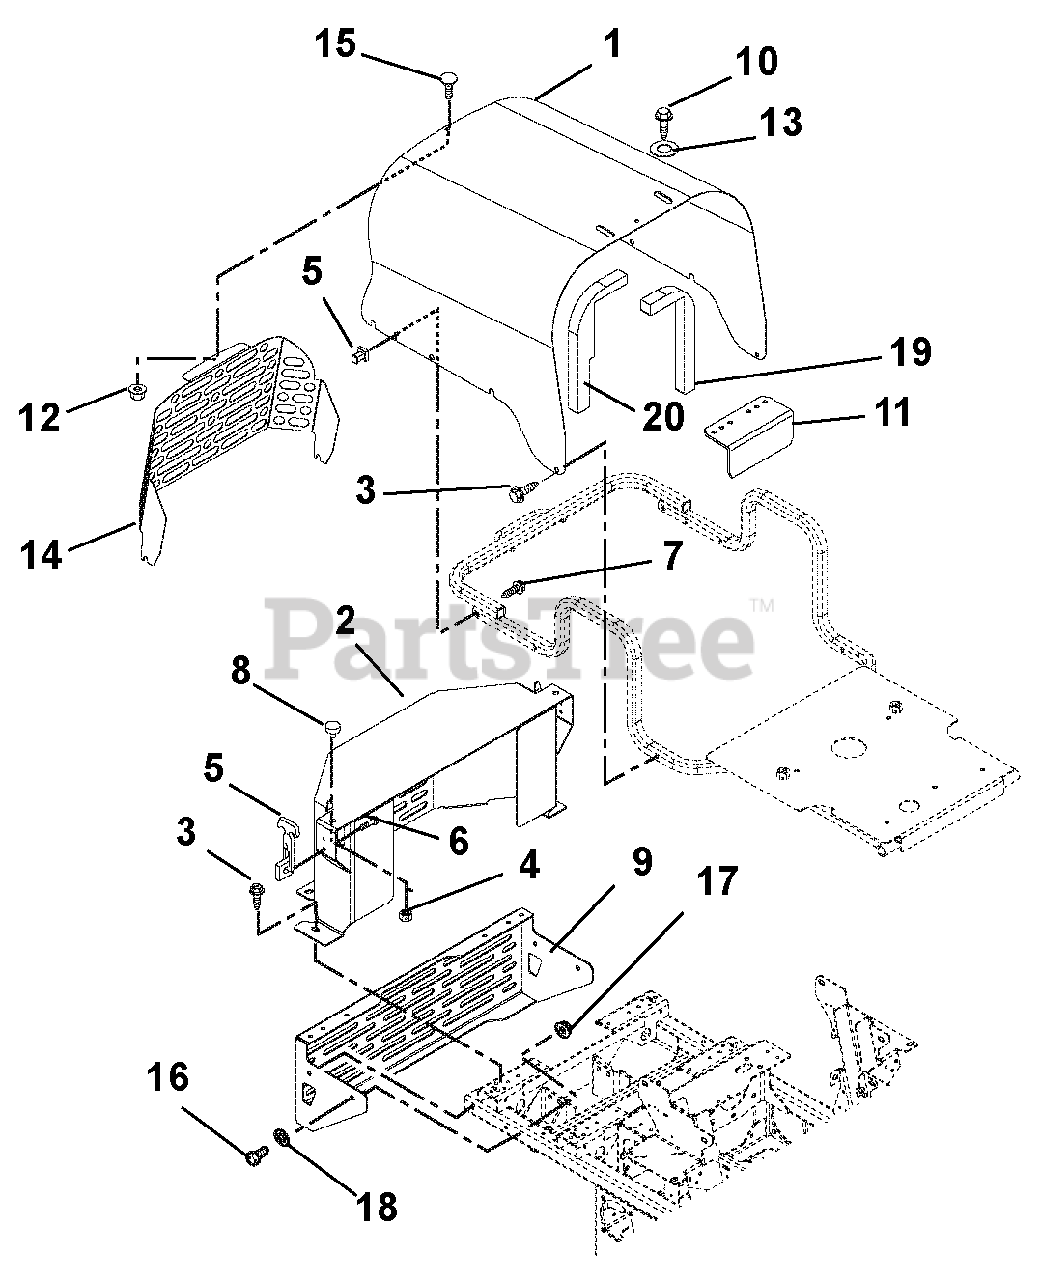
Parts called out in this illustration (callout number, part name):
2	Diesel Belt Guard
3	Screw, Tapping .38-16 x .75 Hex Washer Head
4	Nut, Spin Lock, Flange .312-18
5	Latch, Rubber
6	Screw, Machine 10-24 x .50 Hex Washer Head
7	Screw, Machine 10-24 x 1.50 Hex Washer Head
8	Bumper, Rubber
9	Bumper, Weldment, Rear Diesel
10	Screw, Tapping .25-20 x .50 Hex Washer Head
11	Guard, Radiator Cap
12	Nut, Locking Top Flange .25-20
13	Washer, Flat Steel .281 x .62 x .065
14	Guard, Hood
15	Bolt, Round Head Square Neck .25-20 x .50 Grade 5
16	Bolt, Hex .38-16 x 2.75 Grade 5
17	Nut, Locking Top Flange .38-16
18	Washer, Flat Steel .406 x .812 x.065
19	Dam, Foam Air Left Side
20	Dam, Foam Air Right Side
